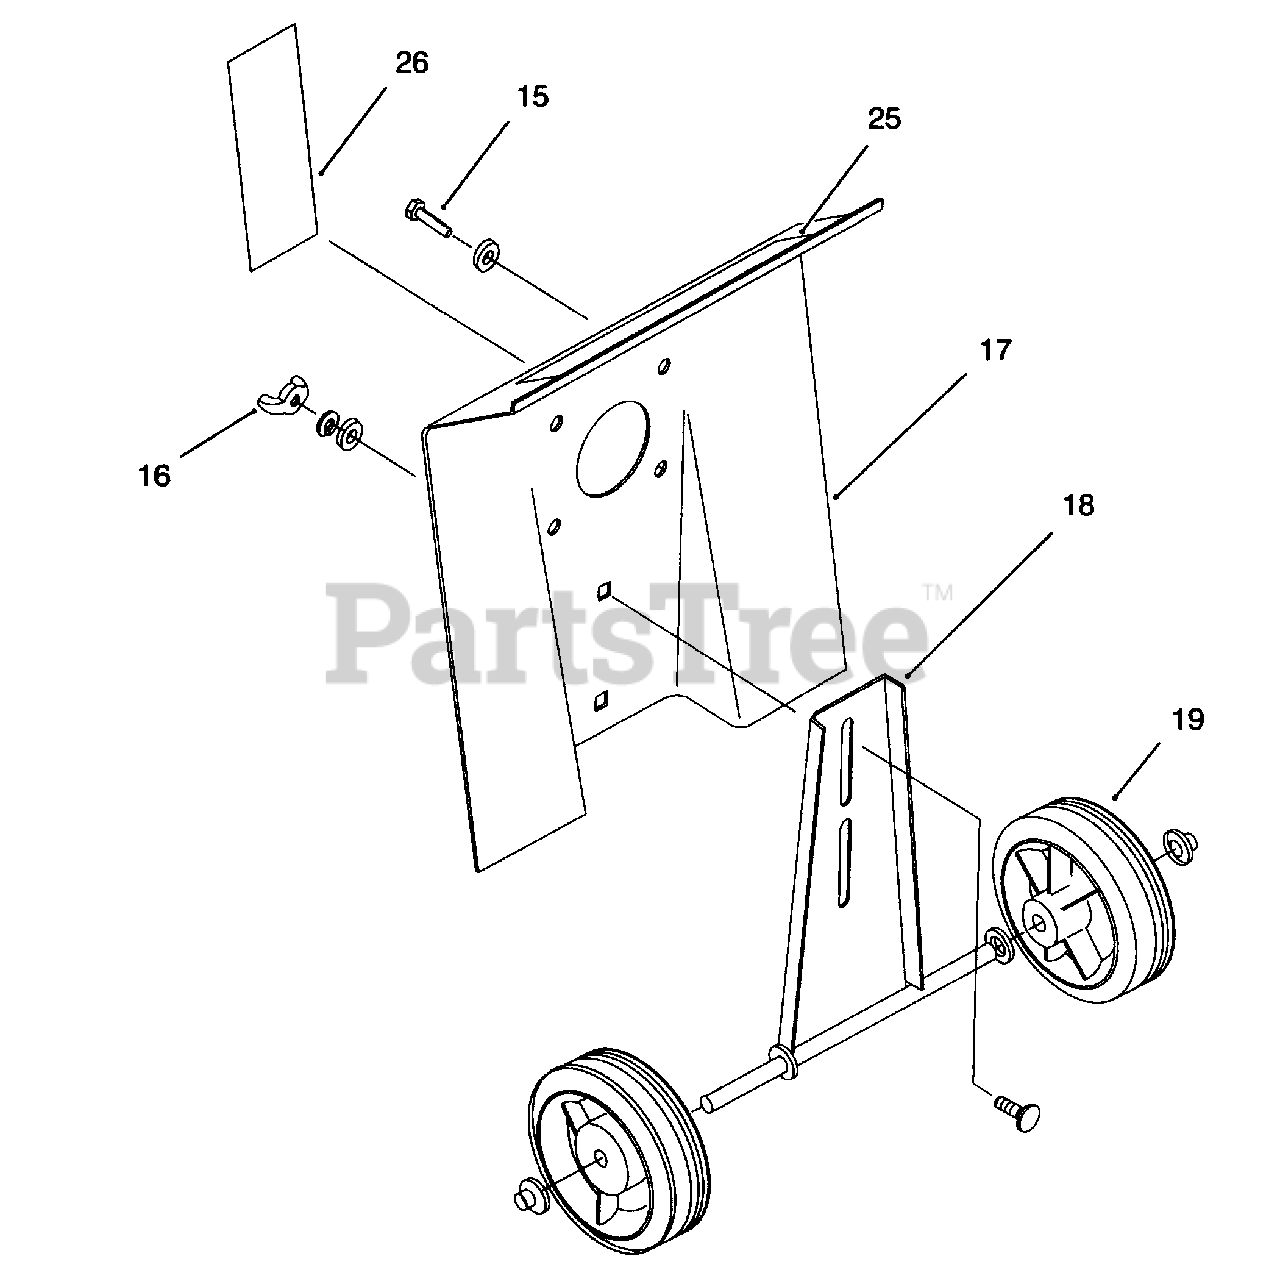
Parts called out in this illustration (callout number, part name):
15	Guard Mounting Hardware
16	Wheel Bracket Mounting Hardware
18	Wheel Bracket Asm.
19	Wheel Asm.
25	Decal-Tine Guard
26	Decal-Tiller Safety Symbol
